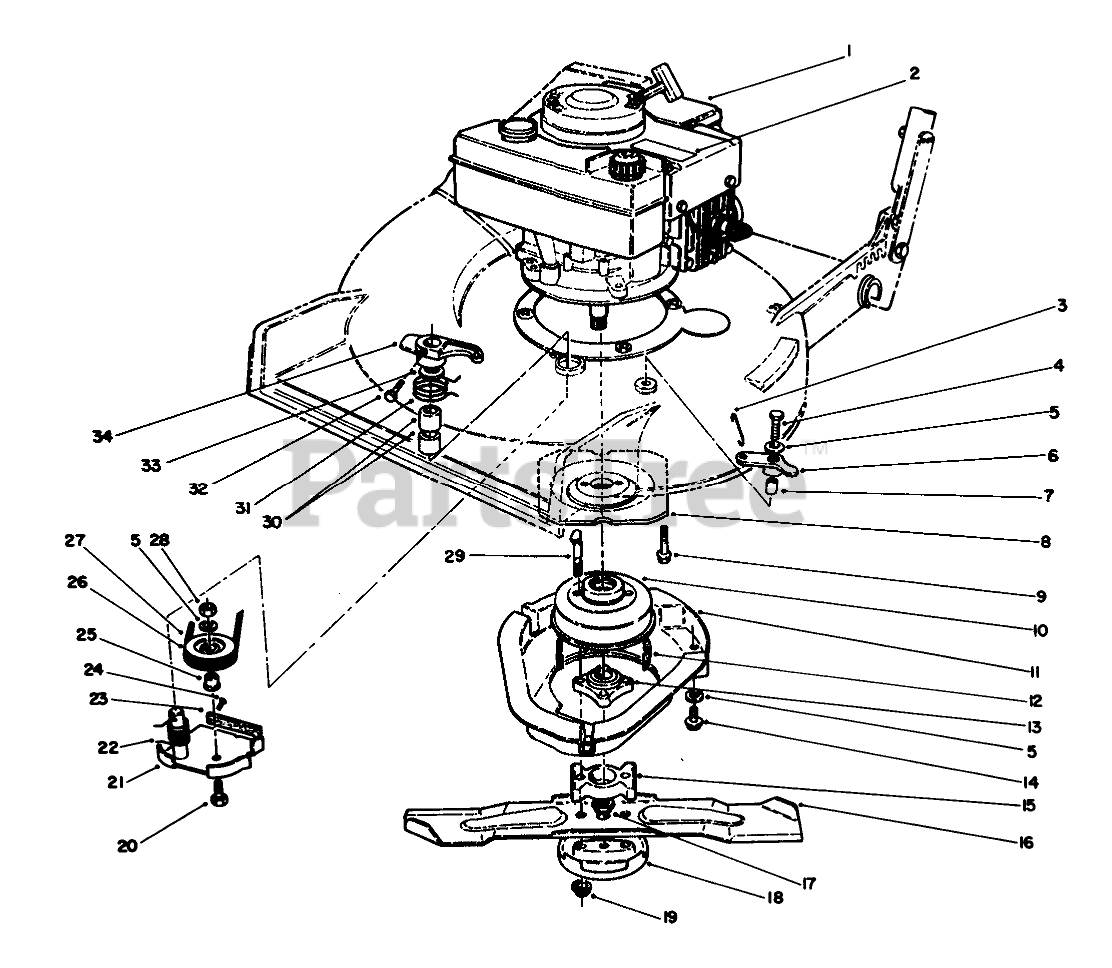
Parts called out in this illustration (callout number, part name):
2	Decal-Engine
3	LINK-CONTROL
4	SCREW-HH
5	WASHER-PLAIN
6	BELLCRANK
7	SLEEVE-BELLCRANK
8	Flywheel
9	3/8-16 X 2 CAPSCREW
10	Drum-Brake
11	SHIELD BBC
12	DAMPENER-VIBRATION
13	HUB ASM
14	SCREW-HWHTF
15	SPACER-BLADE
16	BLADE-21in
17	NUT-LOCK, NI
18	Anti Scalp Cup
19	NUT-LOCK
20	SCREW-HH
21	Brake Plate (Incl. Ref. #23-24)
22	SPRING-TORSION
23	Pad-Brake
24	.185 DIA X .375 RT +
25	HUB-PULLEY, IDLER
26	PULLEY-IDLER
27	V-BELT
28	NUT-LOCK, NI
29	BOLT-BLADE
30	BEARING
31	SPRING-TORSION
32	SCREW-HH
33	WASHER
34	LEVER
